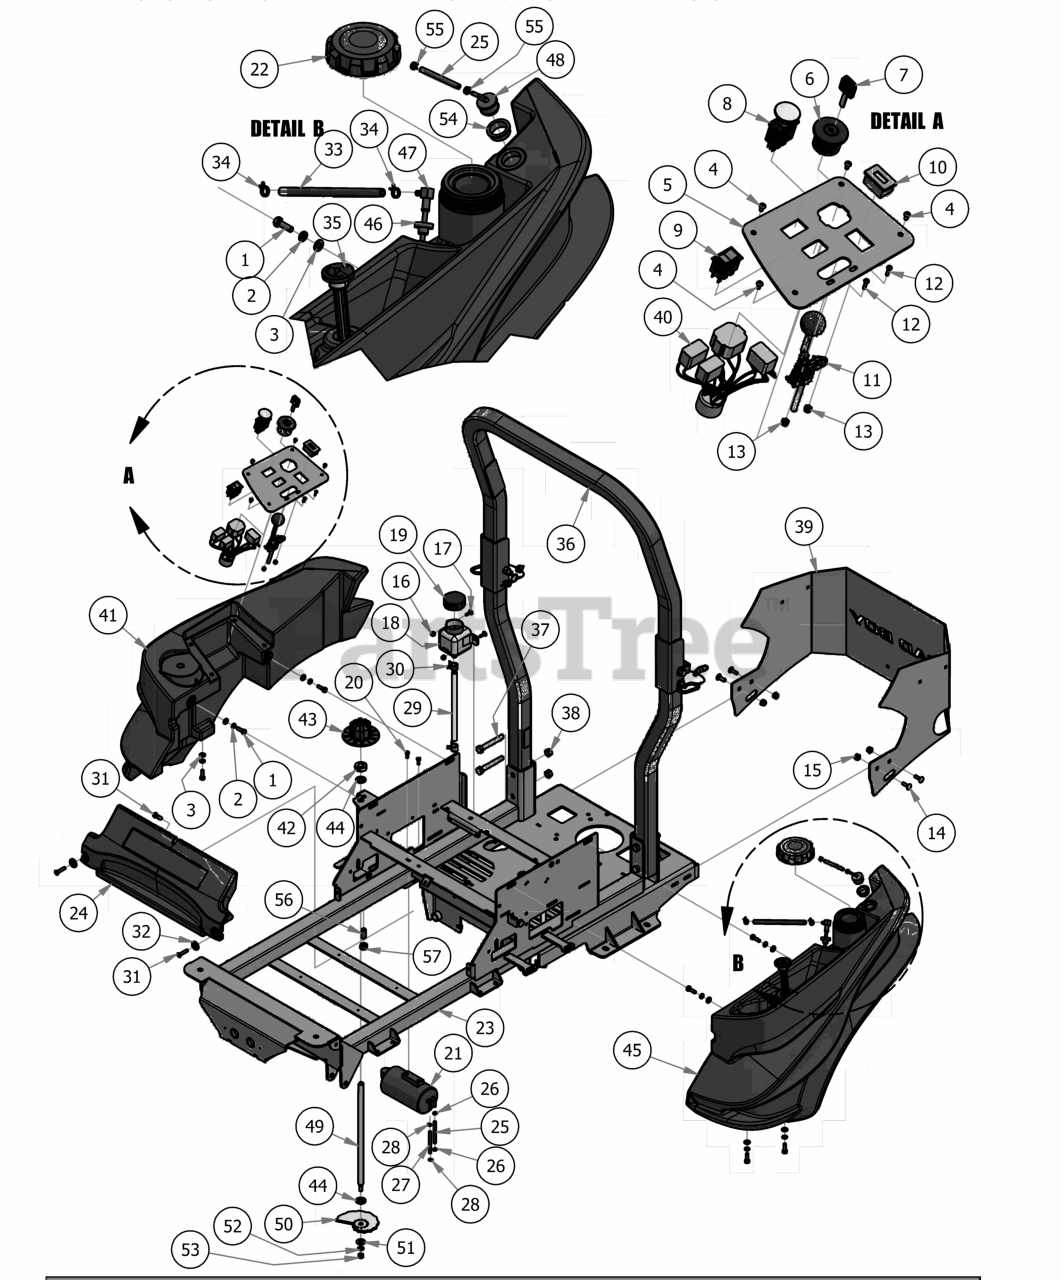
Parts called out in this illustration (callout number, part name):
1	5/16" x 1" Bolt
2	5/16" Lock Washer
3	5/16" Flat Washer
4	10-32 x 3/8" Button Socket Head Bolt
5	Control Panel
6	Ignition Switch
7	Ignition Key
8	PTO Switch
9	Rocker Deck Lift Switch
10	Tachometer
11	Throttle Lever Assembly
12	10-24 X 5/8 BS Button Head Bolt
13	10-24 Nylon Insert Locknut Zinc Orange Nylon
14	5/16" x 1" Carriage Bolt
15	5/16-18 Nylon Flange Nut
16	1/4" Nylock Nut
17	1/4" x 3/4" Carriage Bolt
18	350ml Expansion Tank
19	Hydraulic Tank Cap
20	M6-1.0 X 16MM Hex Bolt
21	Carbon Canister
23	2018 Maverick Frame
24	Front Cover
25	1/4" Vinyl Tubing
26	1/4" Hose Clamp
27	3/16 Vinyl Tubing
28	3/16" Vinyl Hose Clamp
29	3/8" Clear Hose
30	3/8" Hose Clamp
31	5/16-18x1.5 torx cutter -Black
32	1/2" Flat Washer Flat Black
33	1/4" Fuel Line Hose
34	1/4 Fuel Hose Clamp
35	Fuel Gauge w/Grommet
37	1/2-13 x 3 1/2 GR 5 Hex Bolt
38	1/2" Center Lock Nut
39	2017 ZT Rear Plate
40	Universal Wire Harness
41	Right Side Console
42	5/8" Split Collar
43	MZ/ZT Deck Height Dial
44	.630 ID x 1.122 OD x .142 THK Plastic Washer
45	Left Fuel Tank
46	Pick-Up Grommet
48	Rollover Valve
49	2017 Deck Height Dial Rod ZT
50	2017 MZ/ZT Cam Plate
51	3/8" Flat Washer
52	3/8" Lock Washer
53	3/8" Fine Threaded Jam Nut
54	Rollover Valve Grommet
55	3/16 Vinyl Clamp
56	Dial Rod Plunger
57	1/2" Hex Nut
